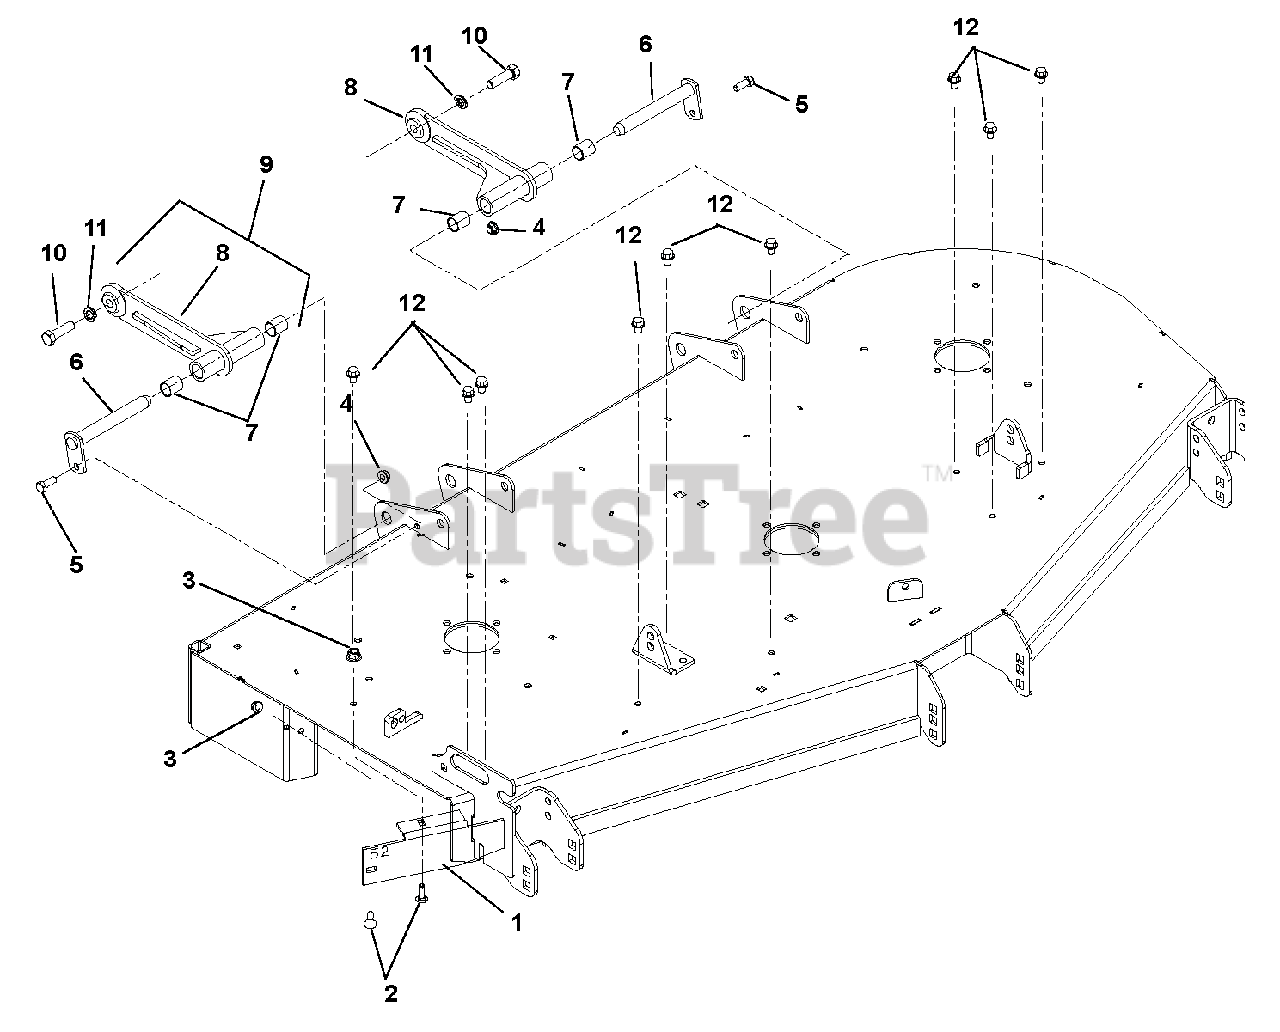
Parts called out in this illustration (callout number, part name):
1	BAFFLE, DISCHARGE 44/48
2	@BLT-RDHDSQNK .31-18X1.00 G5YZ
3	@NUT-LK-NYL-FLG .31-18 YWZC
4	@NUT-LK-NYL-FLG .38-16 YWZC
5	@BLT-HEX .38-16X1.00 GR5 YWZC
6	WELDMENT, MOWER MTG. PIN
7	BRG, .750 X .875 X 1.000
8	DECK PUSHER ARM WMT - BLACK
9	DECK PUSHER ARM ASSEMBLY
10	BLT-HEX .50-13X1.75 GR5EP80 YZ
11	@WSHR-LK .50X.125 REG YWZC
12	@SCR-TAP .38-16X.50 HWH TR YWZ
